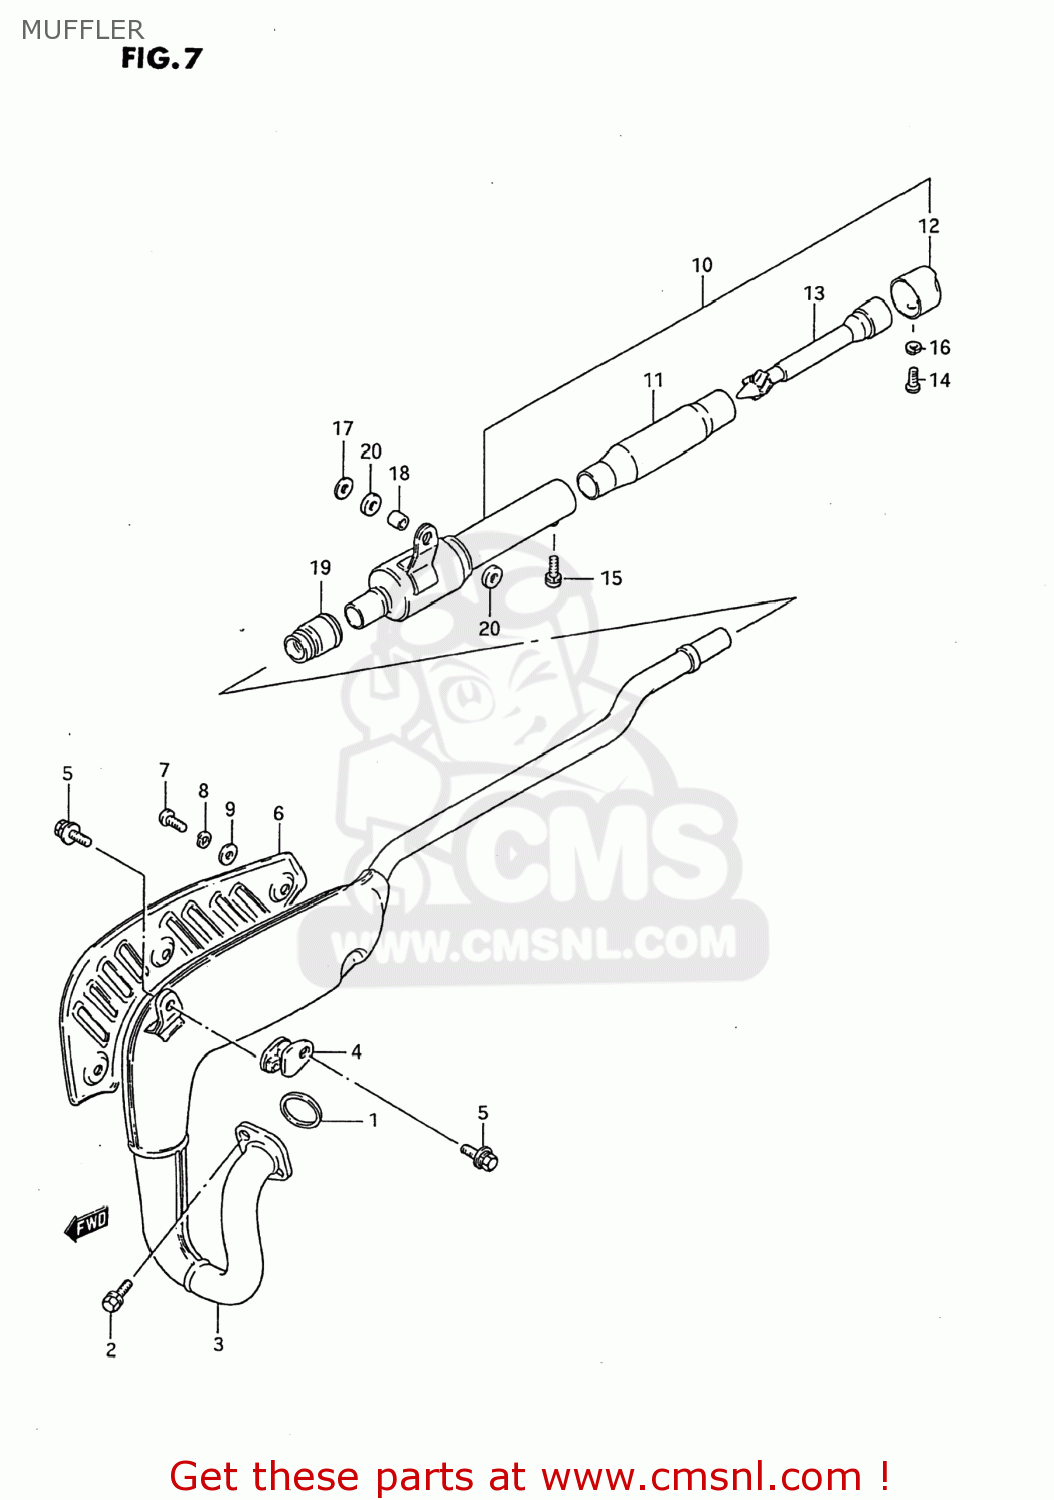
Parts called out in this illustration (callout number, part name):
1	GASKET,EXHAUST (NAS)
2	BOLT
3	BODY,MUFFLER 1ST
4	DAMPER,MUFFLER SUPPORT
5	BOLT
6	COVER,MUFFLER
7	SCREW
8	WASHER,LOCK
9	WASHER
10	MUFFLER ASSEMBLY
11	SHELL,ARRESTER
12	CUTTER,MUFFLER TAIL
13	TUBE,CLEAN OUT
14	SCREW
15	SCREW
16	WASHER,LOCK
17	WASHER
18	SPACER (8.6X13.8X9)
19	CONNECTOR,MUFFLER
20	CUSHION
